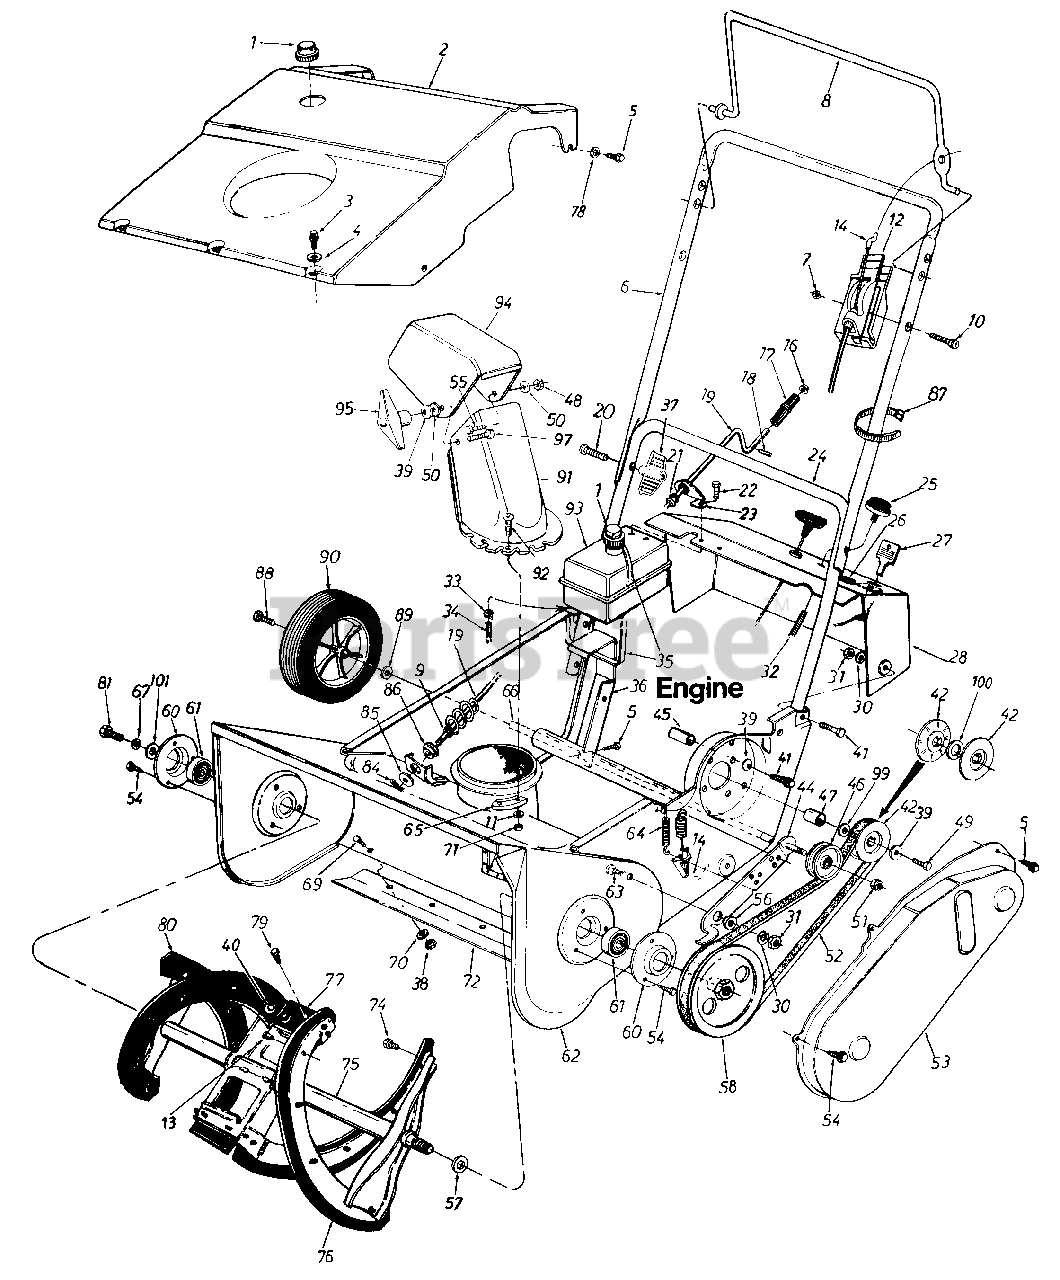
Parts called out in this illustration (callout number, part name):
1	Gas Tank Cap
2	21" Shroud
3	Hex B-Tap Scr. #10 x .38"
4	Spr.-Wash. .206" I.D. x .448"
5	Hex L-Wash. Hd. AB-Tap 1/4 x .62" Lg.
9	Fl-Wash. .385" I.D. x .62"
10	Oval C-Sunk Mach. Scr.
11	Fl-Wash. .281" I.D. x .5" O.D.
12	Throttle Body
13	Pop Rivet .187" Dia.
14	Clutch Cable 35" Lg.
16	Push Cap 3/8" Rod
17	Knob--3/8" Dia. Hole
18	Roll Pin 1/8" Dia. x .63" Lg.
19	Chute Crank Ass'y.
20	Curved Hd. Bolt 5/16-18 x 2" Lg.
21	Plastic Bushing .38" I.D.
22	Hex AB-Tap Scr. 1/4 x .75" Lg.
23	Upper Chute Crank Brkt.
26	Plastic Plug
27	Plastic Key
28	Dash Panel Ass'y.
30	L-Wash. 5/16" I.D.
31	Hex Nut 5/16-18 Thd.
32	Primer Hose--11" Lg.
33	Hose Clamp--1/2" Dia.
34	Gas Line--15" Lg.
35	Cable Tie--17.75" Lg.
38	Hex Jam Nut 1/4-20 Thd.
39	Bell-Wash. 5/16" I.D.
40	Torx AB-Tap Scr. 1/4 x .62" Lg.
41	Hex Bolt 5/16-18 x 1.5" Lg.
42	3/8" "V"-Pulley Half .625" I.D. x 6.0" O.D.
46	Fl-Idler w/Flanges 2.12" O.D.
47	Spacer .635" I.D. x .89" O.D. x .57"
48	Hex L-Nut 5/16-18 Thd.
49	Hex Bolt 5/16-24 x .75" Lg.
50	Fl-Wash. .344" I.D. x 1.25"
51	Hex Patch L-Nut 3/8-24 Thd.
52	"V"-Belt
54	Hex B-Tap Scr. 1/4" x .38" Lg.
55	Carriage Bolt 5/16-18 x .75"
56	Shld. Spacer .50" Dia. x .27"
57	Fl-Wash. .510" I.D. x 1.0" O.D.
58	3/8" "V"-Pulley 1/2-20 L.H. x 6"
64	Extension Spring 1.12" Lg.
65	Chute Flange Keeper
66	Wheel Axle 1/2" O.D. x 20.6" Lg.
67	L-Wash. 1/4" I.D.
69	Carriage Bolt 1/4-20 x .50"
70	Fl-Wash. .281" I.D. x .73"
71	Hex L-Nut 1/4-20 Thd.
72	Shave Plate
74	Hex Wash. B-Tap Scr. 1/4 x .62" (Spec.)
76	Rubber Spiral--L.H.
77	Rubber Paddle
78	Flat Washer
79	Hex Wash. B-Tap Scr. #10 x .62" Lg.
80	Rubber Spiral--R.H.
81	Hex Wash. TT-Tap Cl-Scr. 1/4-20 x .75" Lg.
84	Cotter Pin 3/32" Dia. x .75"
85	Fl-Wash. .406" I.D. x 1.25"
86	Hex Bushing .385" I.D.
87	Cable Tie
88	Hex Tap Scr. 3/8-24 x .5" Lg.
89	Fl-Wash. .510" I.D. x .75"
90	Wheel & Tire Ass'y. 7" x 1.5"
91	Lower Chute
92	Truss Mach. Scr. 1/4-20 x .75"
93	Fuel Tank--One Qt.
94	Upper Chute
95	Knob
97	Carriage Bolt 5/16-18 x 1"
99	Fl-Wash. .635" I.D. x 1.04" O.D.
100	Fl-Wash. .635" I.D. x .93" O.D.
101	Fl-Wash. .25" I.D. x .93"
